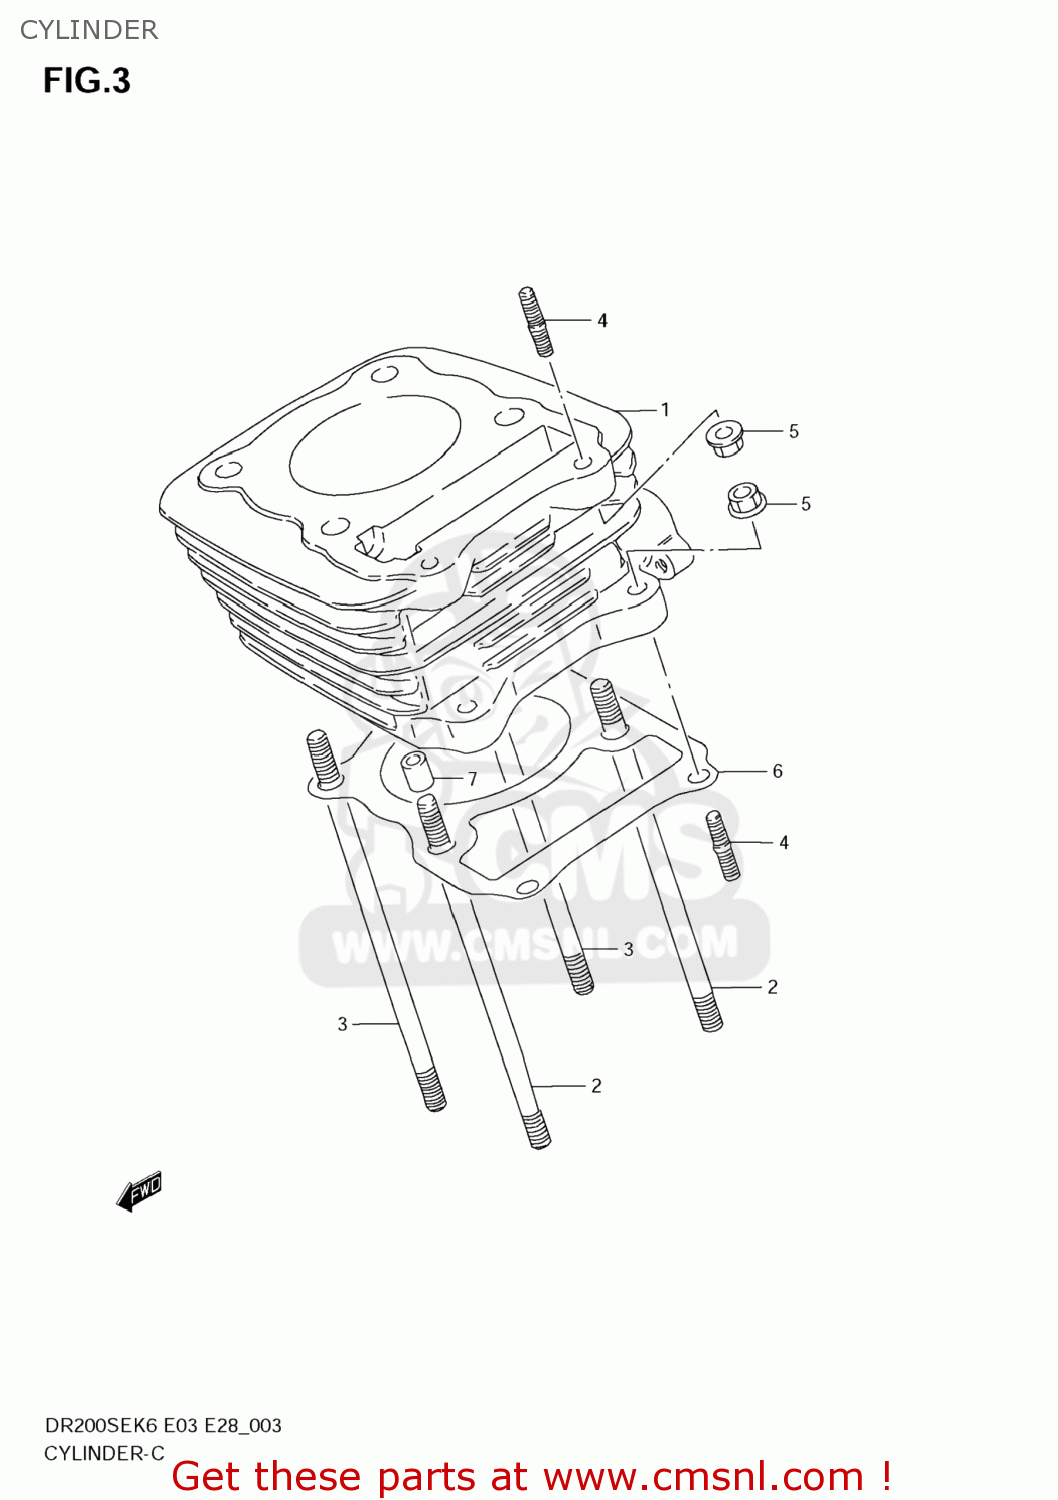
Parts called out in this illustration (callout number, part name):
1	CYLINDER
2	BOLT,STUD
3	BOLT,STUD(8X167)
4	BOLT,STUD
5	NUT
6	GASKET,CYLINDER (NAS)
7	PIN
